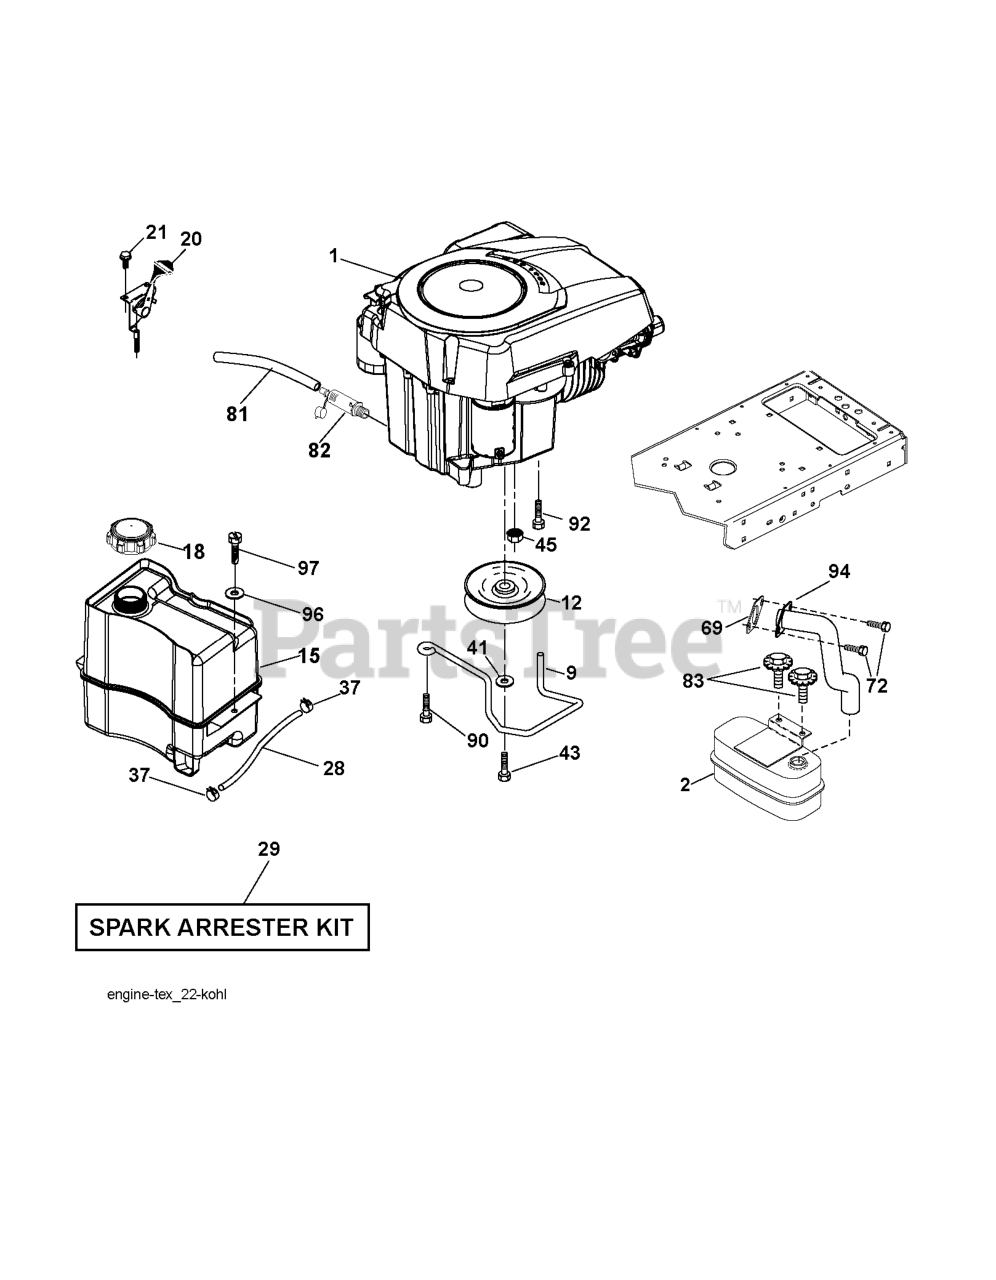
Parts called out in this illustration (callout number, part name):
2	MUFFLER.SINGLE.CYL.KOHL/B&S
9	KEEPER.BELT.ENGINE.4.2
12	PULLY ENGINE
15	RP TANK FUEL FRT 1.5 GAL
18	FUEL CAP
20	CONTROL.TH/CK.C.
21	SCREW
28	LINE.FUEL.20
29	KIT.SPARK ARRESTOR 794945 B&S
37	HOSE CLAMP
41	LOCKWASHER
43	BOLT HEX 7/16-20X4-1/4"
45	NUT
69	GASKET.EXHAUST.KOHLER
72	SCREW.SOCKET HD.5/16-1
81	TUBE, DRAIN OIL ASM.
82	PLUG DRAIN OIL EASY
83	BOLT.5/16-18UNCX3/4 W/SEMS.BLK
90	SCREW 3/8-16X1
92	SCREW 3/8-16X1
94	RP.TUBE.EXHAUST.KOHL.COURAGE
97	SCREW HEXWSHR 1/4-20X3/4
